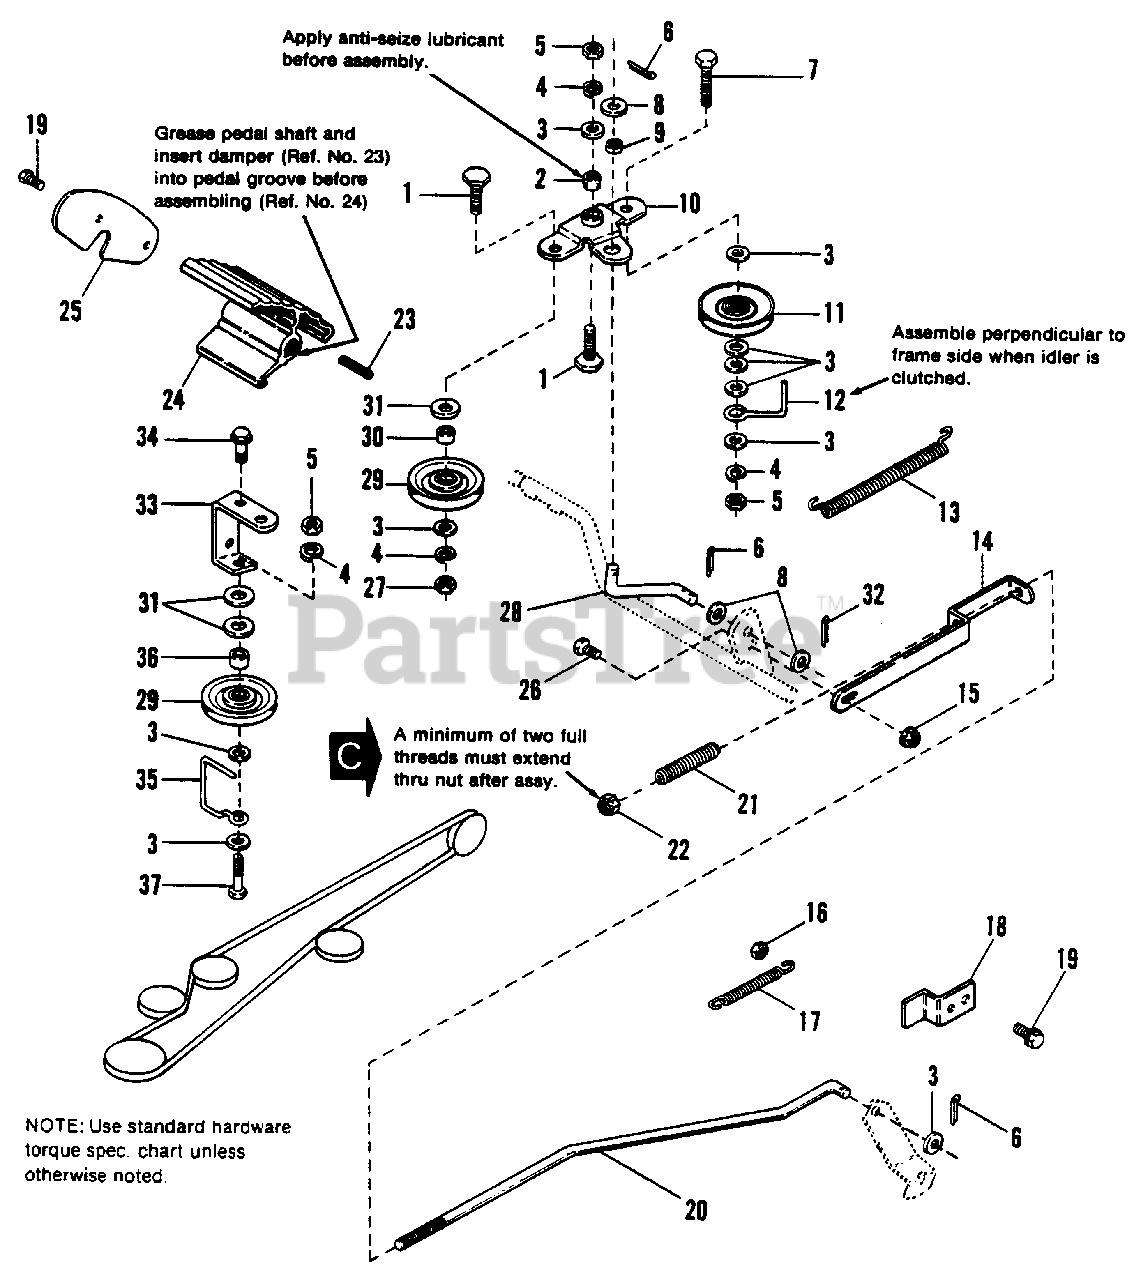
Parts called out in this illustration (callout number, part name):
1	SCREW, Hex, 3/8-16 x 1-1/4, Thin Hd.
3	WASHER, Plain, 5/16
4	LOCKWASHER, 3/8
5	NUT, Hex, 3/8-16
6	PIN, cotter, 3/4
7	CAPSCREW, Hex Hd., 3/8-16 x 1-3/4
8	WASHER, Plain, 13/32 x 7/8, 14 Ga.
9	BUSHING, Ball
10	ARM ASSY., Clutch
11	PULLEY, Idler
13	SPRING, Tension, Clutch
15	NUT, Hex, Flange Lock, 3/8-16
16	NUT, Jam Lock, 3/8-16
17	SPRING, Brake Return
18	STOP, Brake Lever
19	SCREW, Taptite, 1/4-20 x 1/2
20	ROD, Brake
22	NUT, Hex Lock, 5/16-18
23	DAMPER, Rubber
24	PEDAL, Foot
25	PLATE, End
26	CAPSCREW. Hex, 3/8-16 x 3/4
27	NUT, Hex, Jam, 3/8-16
28	LINK, Clutch Arm
29	PULLEY ASSY.
31	WASHER, 13/32 x 1.10 Ga. Plain
32	PIN, coner, 1
33	BRACKET, Idler
34	SCREW, Taptite, 5/16-18 x 1/6
37	CAPSCREW, 3/8-16 x 1-3/4
